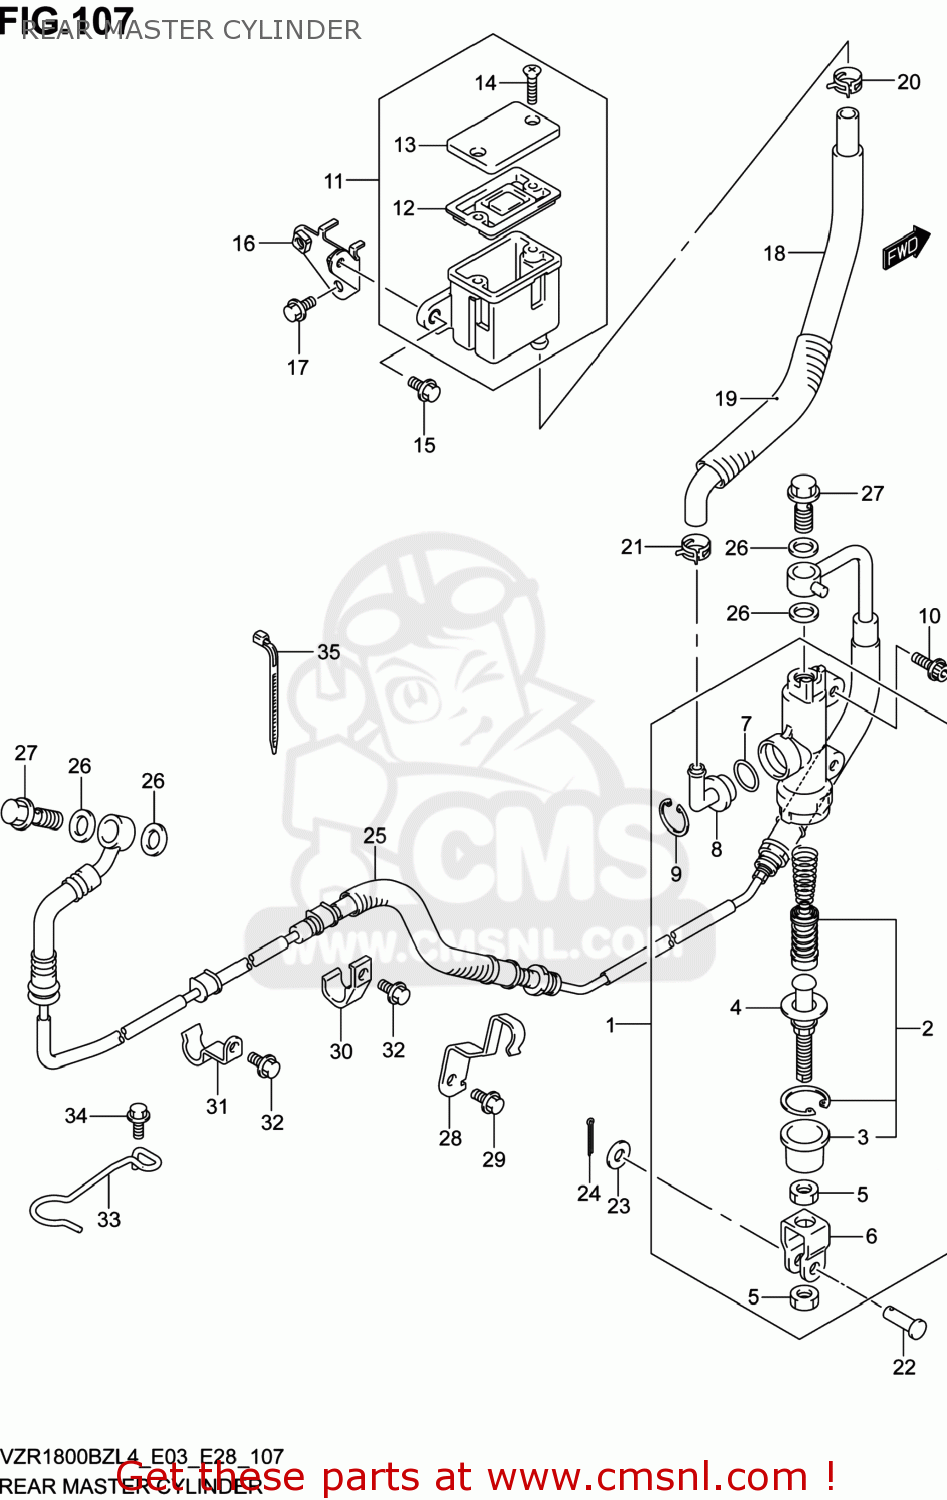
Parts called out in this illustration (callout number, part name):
1	CYLINDER ASSY,RR MASTER
2	PISTON/CUP SET
3	BOOT
4	ROD,PUSH
5	NUT
6	YOKE
7	O RING
8	CONNECTOR
9	CIRCLIP
10	BOLT
11	TANK ASSY,RR RESERVOIR
12	DIAPHRAGM
13	CAP
14	SCREW
15	BOLT
16	BRACKET,RR RESERVOIR TANK
17	BOLT
18	HOSE,RR RESERVOIR TANK
19	HEATSHIELD,RR RSVR TANK HOSE
20	CLIP
21	CLIP
22	PIN(6X18.2)
23	WASHER
24	PIN
25	HOSE ASSY,RR BRAKE
26	WASHER(10X15X1.5)
27	BOLT UNION
28	CLAMP,RR BRAKE HOSE NO.3
29	BOLT
30	CLAMP,RR BRAKE HOSE
31	CLAMP,RR BRAKE PIPE
32	BOLT
33	GUIDE,RR BRAKE HOSE
34	BOLT
35	CLAMP(L:165)
